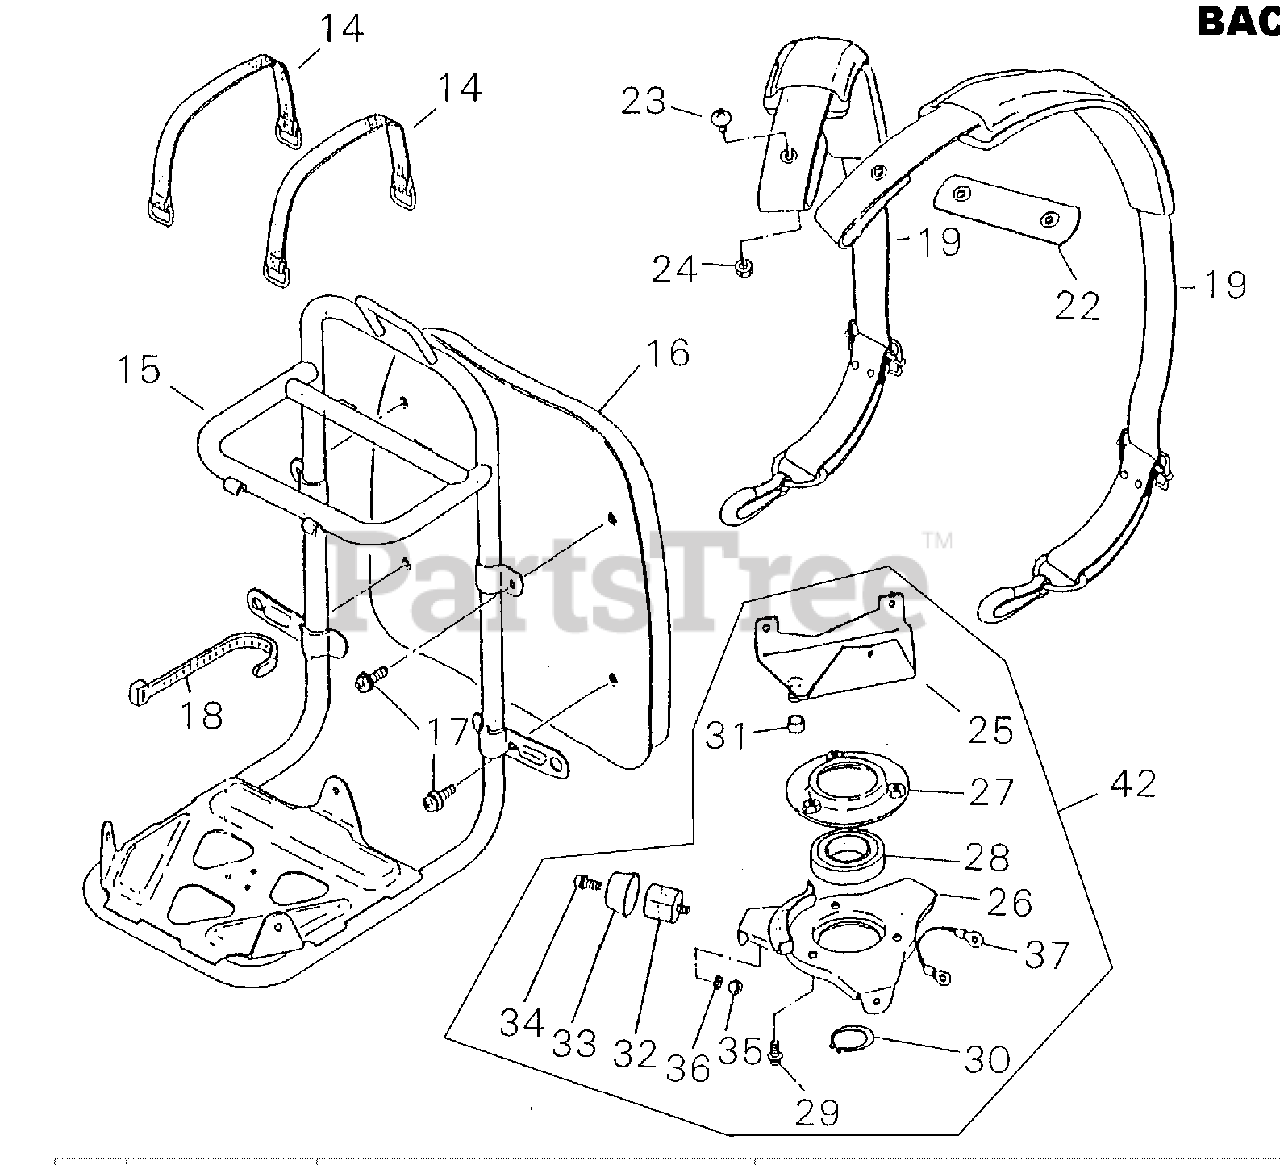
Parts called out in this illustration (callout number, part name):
14	STRAP
15	FRAME, BACKPACK
16	PAD
17	SCREW - 5X12
18	CLAMP
19	HARNESS ASSY
22	BAND
23	SCREW - 6X14
24	LOCKNUT - 6
25	BRACKET - UPPER
26	BRACKET - LOWER
27	RETAINER
28	BEARING, BALL - 6005ZZ
29	SCREW - 5X10
30	RING, RETAINING - 25
31	CUSHION, STOP
32	CUSHION
33	HOLDER, MOUNT
34	SCREW - 5X10
35	NUT - 5
36	LOCKWASHER - 5
37	LEAD - GROUND
42	BRACKET ASSY
